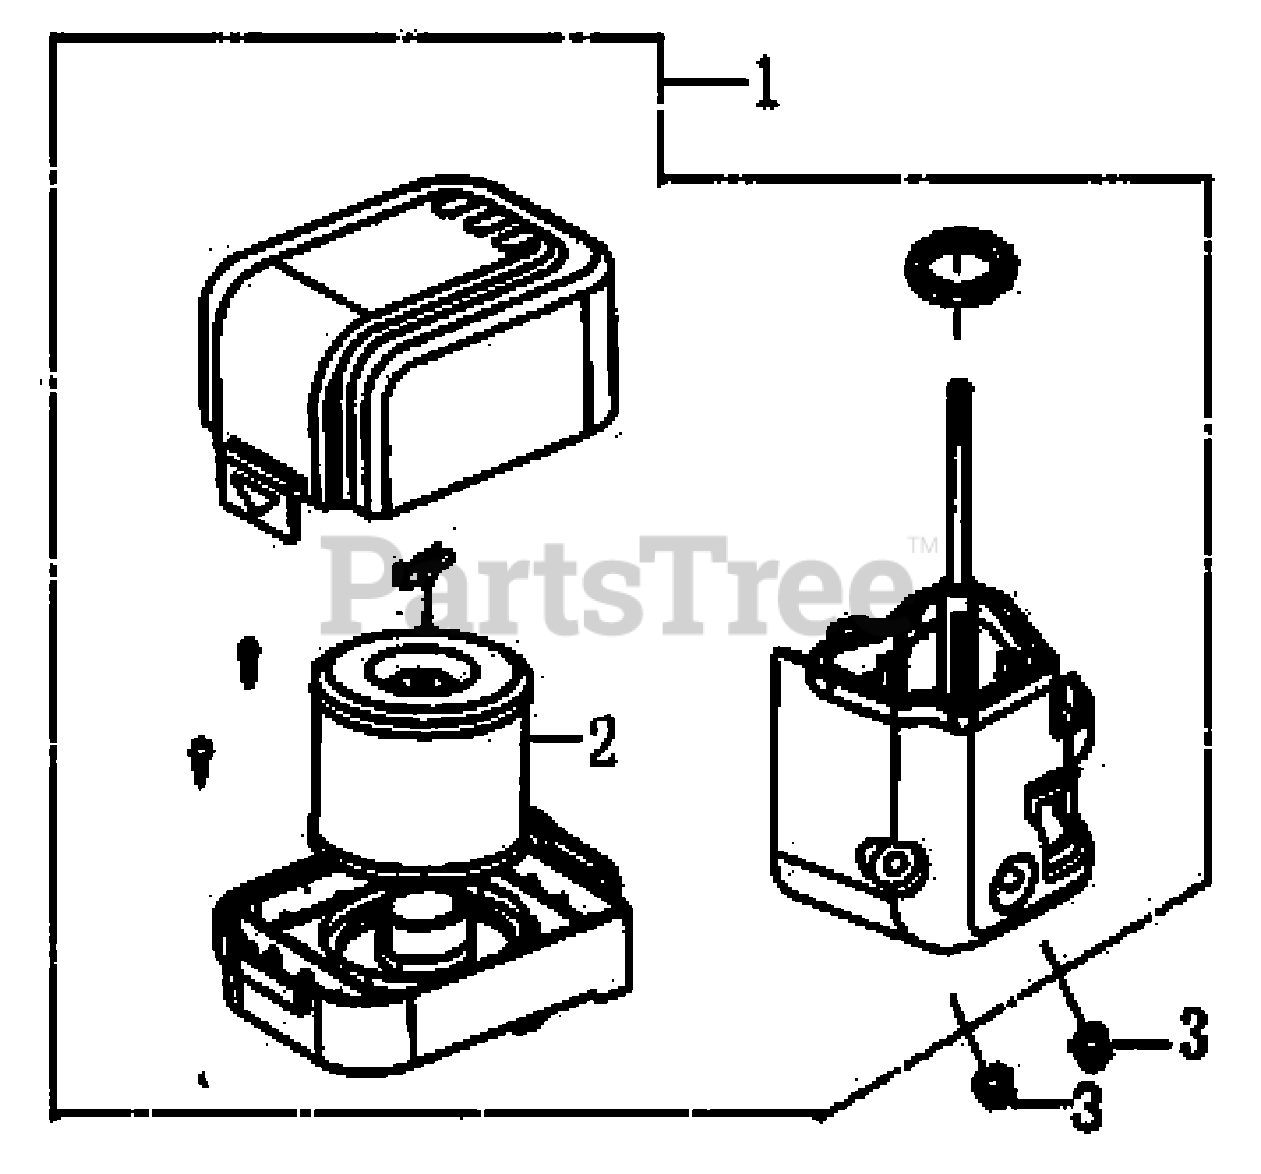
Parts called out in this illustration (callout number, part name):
1	AIR CLEANER ASSEMBLY
2	ELEMENT ASSEMBLY, AIR CLEANER
3	NUT, FLANGE, 6MM
